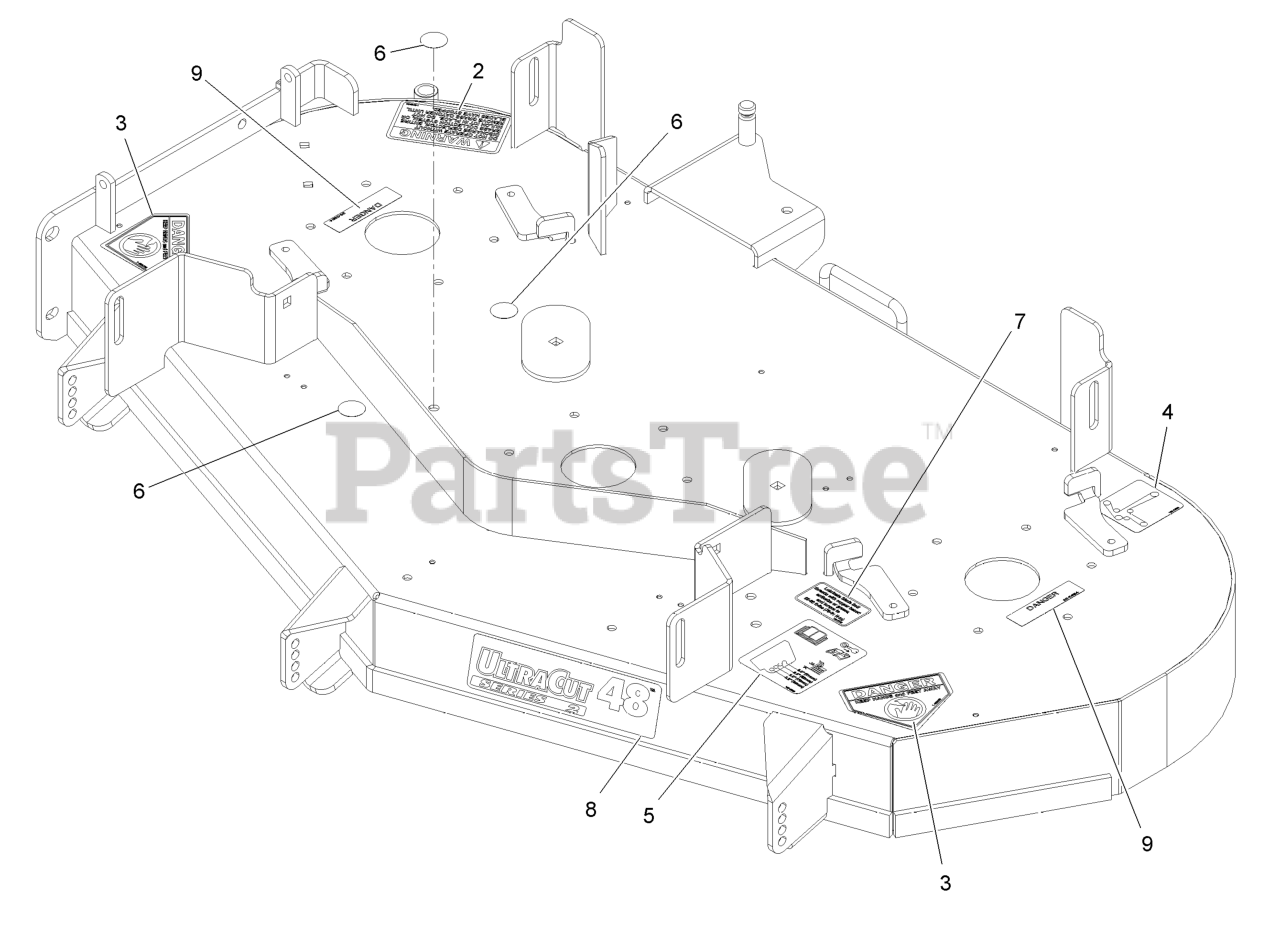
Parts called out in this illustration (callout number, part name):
2	DECAL-WARNING, DISCHARGE
3	DECAL-DANGER
4	DECAL-ROUTING, BELT
5	DECAL-ROLLER, ANTI-SCALP
6	DECAL-HOLE COVER
7	DECAL,BOLT TORQUE
8	DECAL-ULTRACUT 48 SERIES
9	DECAL-COVER, MISSING
